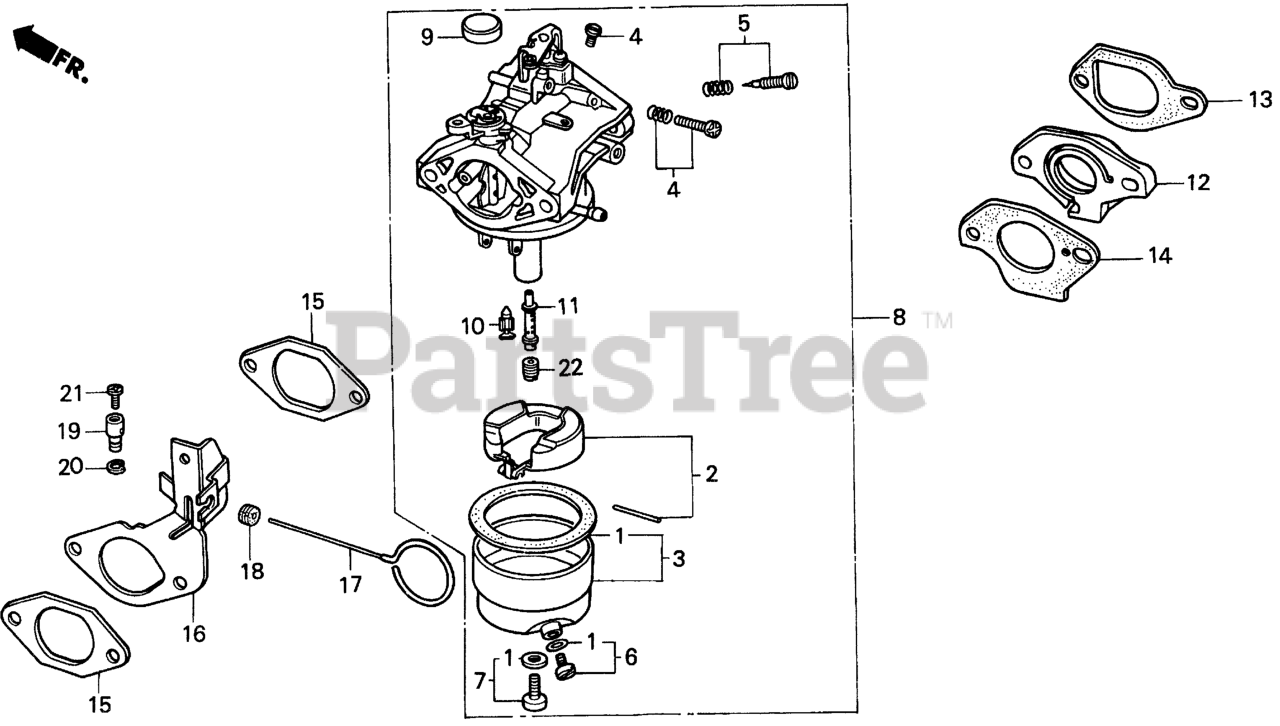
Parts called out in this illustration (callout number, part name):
1	GASKET SET
2	FLOAT SET
3	CHAMBER SET, FLOAT (CARBURETOR NO.) (NOT AVAILABLE)
4	SCREW SET A
5	SCREW SET A
6	SCREW SET, DRAIN
7	SCREW SET B
7	SCREW SET
8	CARBURETOR ASSY. (BB49B B) (NOT AVAILABLE)
9	CAP, CHOKE LEVER DUST
10	VALVE, FLOAT
11	NOZZLE, MAIN
12	INSULATOR, CARBURETOR
13	GASKET, INSULATOR
14	GASKET, CARBURETOR
15	GASKET, AIR CLEANER
16	STAY, CHOKE CONTROL
17	ROD, CHOKE CONTROL
18	GROMMET, CHOKE ROD
19	HOLDER, CABLE
20	CIRCLIP (5MM) Use from Engine SN 2327377.
21	SCREW, PAN (4X8)
22	JET, MAIN (#82)
22	JET, MAIN (#85)
22	JET, MAIN (#88) Use from Engine SN BE27A B to BE27A E.
